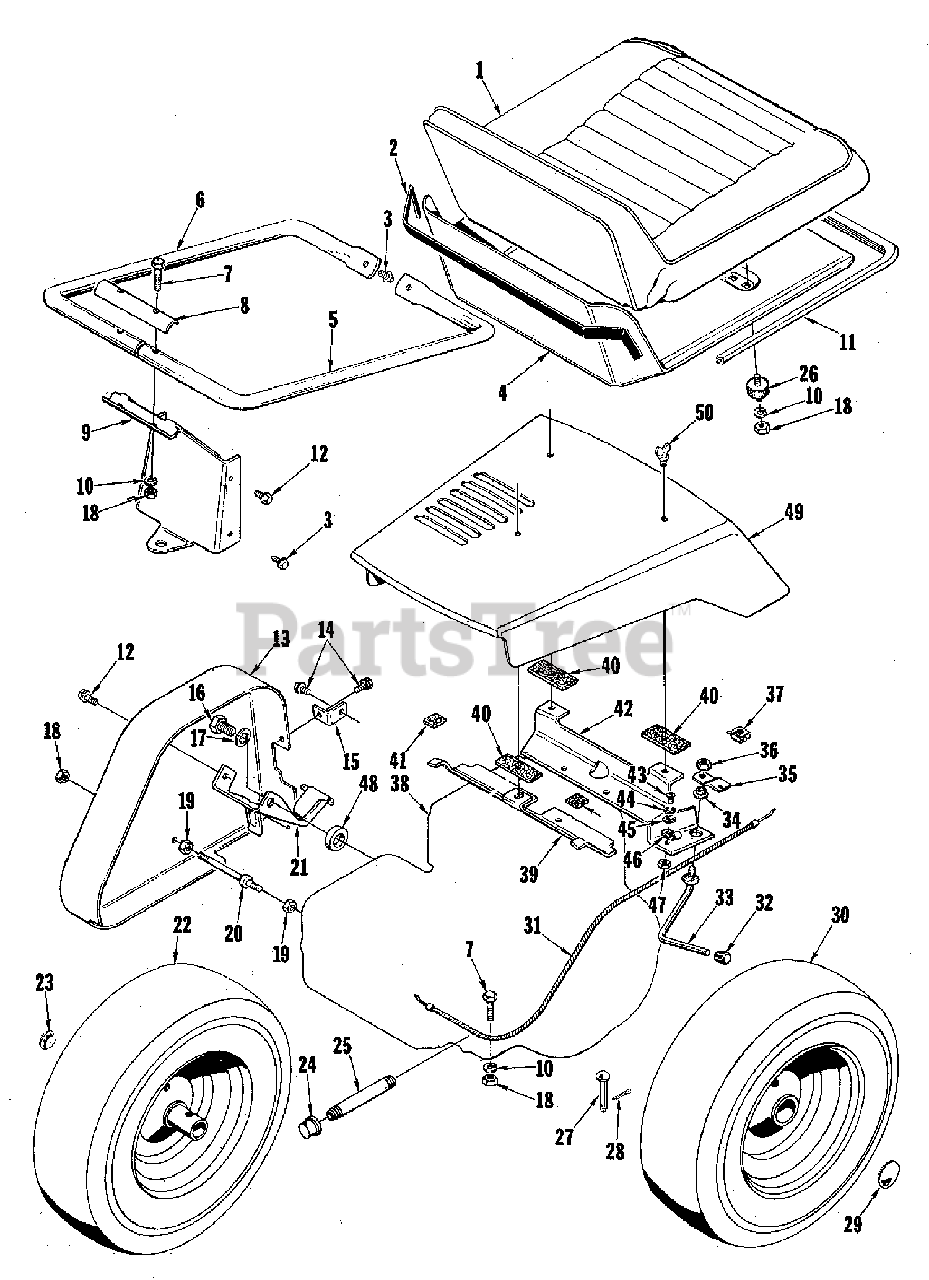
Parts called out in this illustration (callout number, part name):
2	TAPE, Seat Pan
3	SCREW, Taptite, 1/4-20 x 1/2
5	HANDLE, R.H., Rear
6	HANDLE, L.H., Rear
7	SCREW, Hex Cap, 5/16-18 x 1-1/2
8	BRACKET, Handle Support
9	PLATE, Hitch, Rear
10	WASHER, Lock, 5/16
11	TRIM, "U" Channel
12	SCREW, Hex Swage, 5/16-18 x 1/2
13	GUARD, Pulley
14	SCREW, Hex Taptite, 5/16-18 x 3/8
15	BRACKET, Pulley Guard
16	SCREW, Hex Cap, 1/2-20 x 3/4
17	WASHER, Lock, 1/2
18	NUT, Hex, 5/16-18
19	NUT, Hex Lock, 5/16-18
20	STUD, Pulley Guard
22	WHEEL & TIRE, L.H., Rear, 4.8 x 4.0 x 8
23	BUTTON, Plug
25	NIPPLE, Pipe
26	CONNECTOR, Cushion
28	PIN, Cotter, 1/8 x 3/4
29	BUTTON, Plug
30	WHEEL & TIRE, R.H., Rear, 4/8 x 4.0 x 8
31	CABLE & WIRE, Throttle
34	WASHER, Throttle
35	ARM, Throttle
36	NUT, Hex Lock, 3/8-16
37	NUT, Tinnerman
38	ENGINE, 5 HP
39	SUPPORT, Hood, Rear
40	GASKET, Felt
41	GASKET, Felt
42	SUPPORT, Hood, Front
43	SCREW, Round, #10-32 x 1/2
44	WASHER, Lock, Extension Tooth #10
45	WASHER, Flat, #10
47	NUT, Hex, #10-32
48	WASHER, Flat, 1/2
50	SCREW, Thumb, 5/16-18 x 3/4
